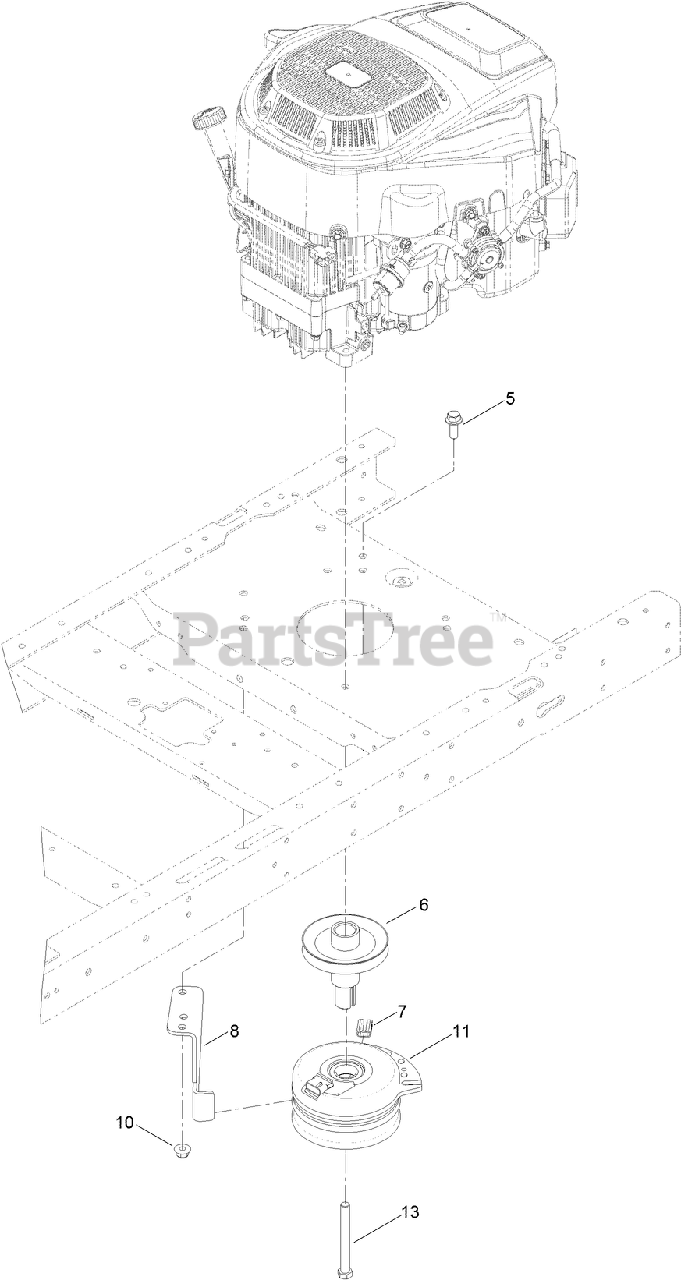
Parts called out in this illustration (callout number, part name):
5	SCREW-HHF
6	PULLEY-ENGINE
7	ISOLATOR-CLUTCH
8	STOP-CLUTCH (NARROW)
10	NUT-HF, NI
11	CLUTCH-ELECTRIC
13	SCREW-HH
